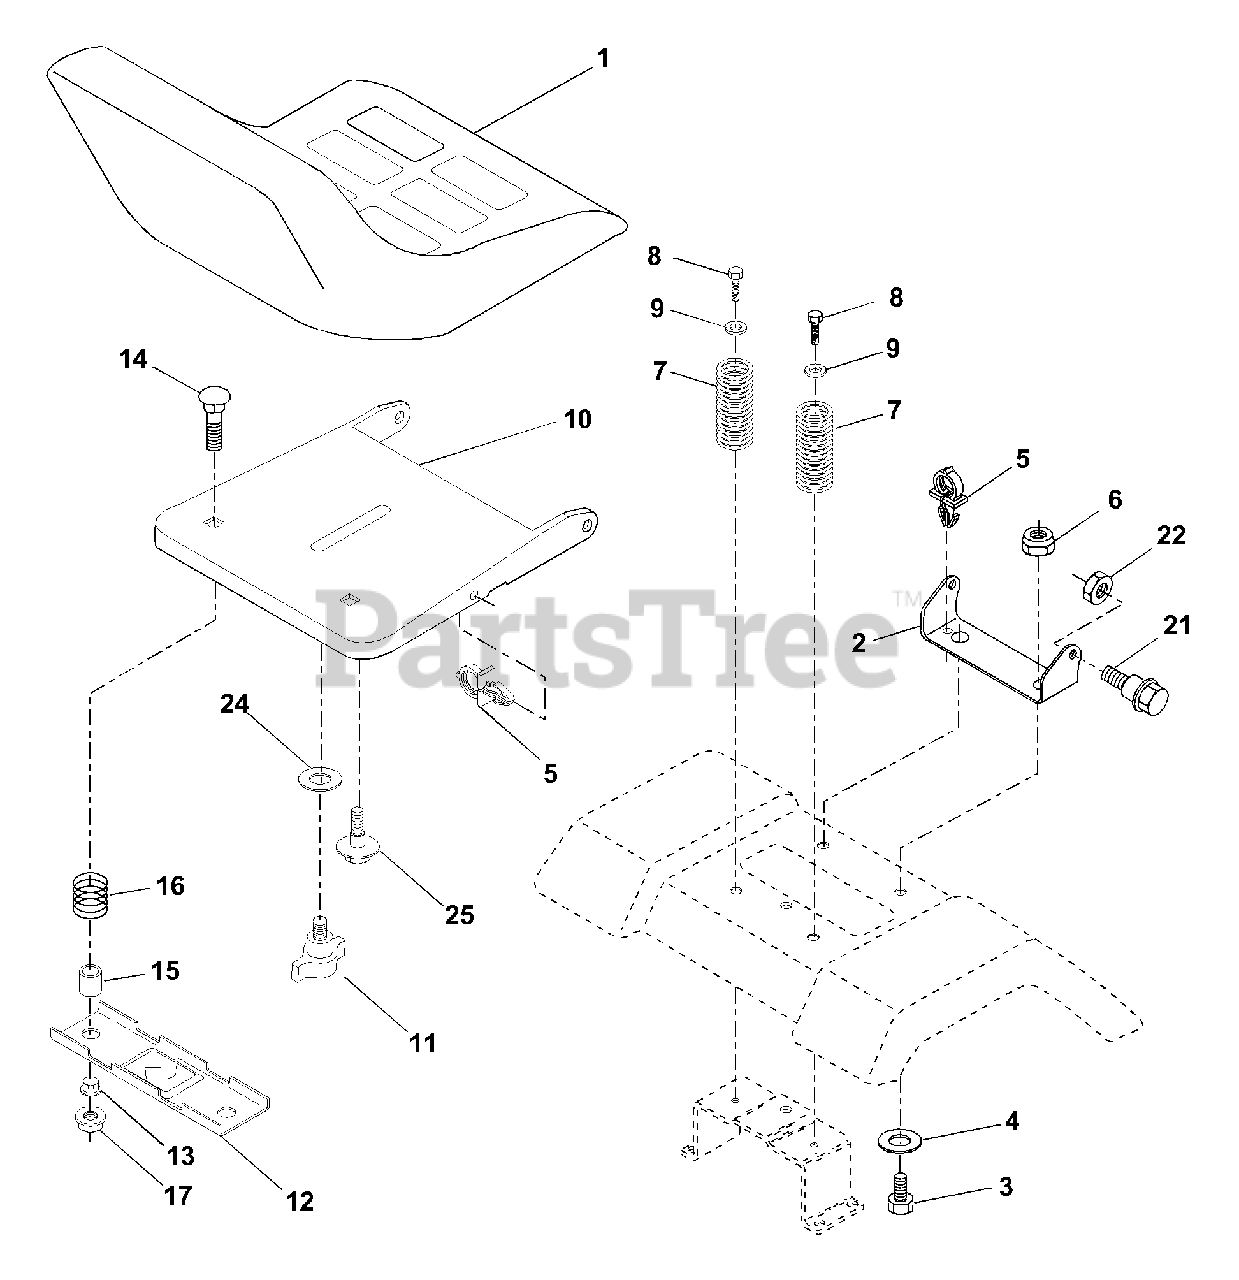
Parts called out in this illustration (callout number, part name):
1	Seat
2	Bracket Pivot Seat 8 720
3	Bolt Fin Hex 3/8-16unc X 1
4	Washer 13/32 X 1 X 10 Ga
5	Clip Push-In
6	Nut Hex w/Ins. 3/8-16 Unc
7	Spring Seat Cprsn 2 250 Blk Zi
8	Screw 3/8-16 x 1.5 Smgml
9	Washer 13/32 X 1 X 14 Ga.
10	Pan Seat
11	Knob Seat
12	Bracket Mounting Switch
13	Bushing Snap Blk Nyl 50 Id
14	Bolt Rdhd Sqnk 1/4-20x1-1/2
15	Spacer Split 28x 88
16	Spring Cprsn
17	Nut Lock 1/4 Lge Flg Gr 5 Zinc
21	Bolt Shoulder 5/16-18 Unc
22	Nut Hex Lock W/Ins 5/16-18
24	Washer 17/32 X 1-3/16 X 12 Ga.
25	Bolt Shoulder 5/16-18 X 62
